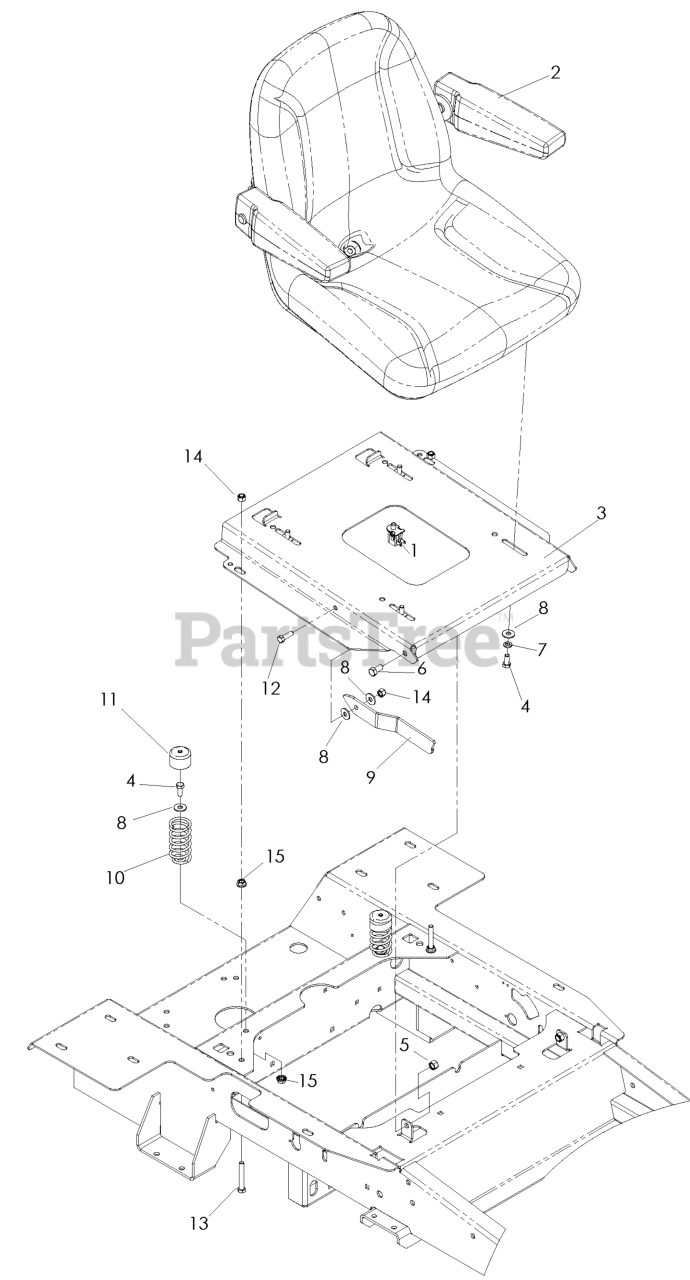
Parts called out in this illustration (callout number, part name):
1	SEAT SWITCH
2	SEAT W/ARMRESTS
3	PAN, SEAT, BLK
4	HCS 5/16C X 3/4
5	NUT 3/8-16 NYLOC
6	SCREW 3/8C X 3/4 HEX CAP
7	WASHER.LOCK.HVY.HLCL.SPR.5/16
8	WASHER 5/16 FLAT
9	ARM, PROP, SEAT
10	SEAT SPRING
11	SPRING CAP
12	HCS 5/16C X 1
13	TAP BOLT 5/16C X 2 1/4
14	NUT 5/16 NYLOC
15	NUT 5/16C WHIZ
